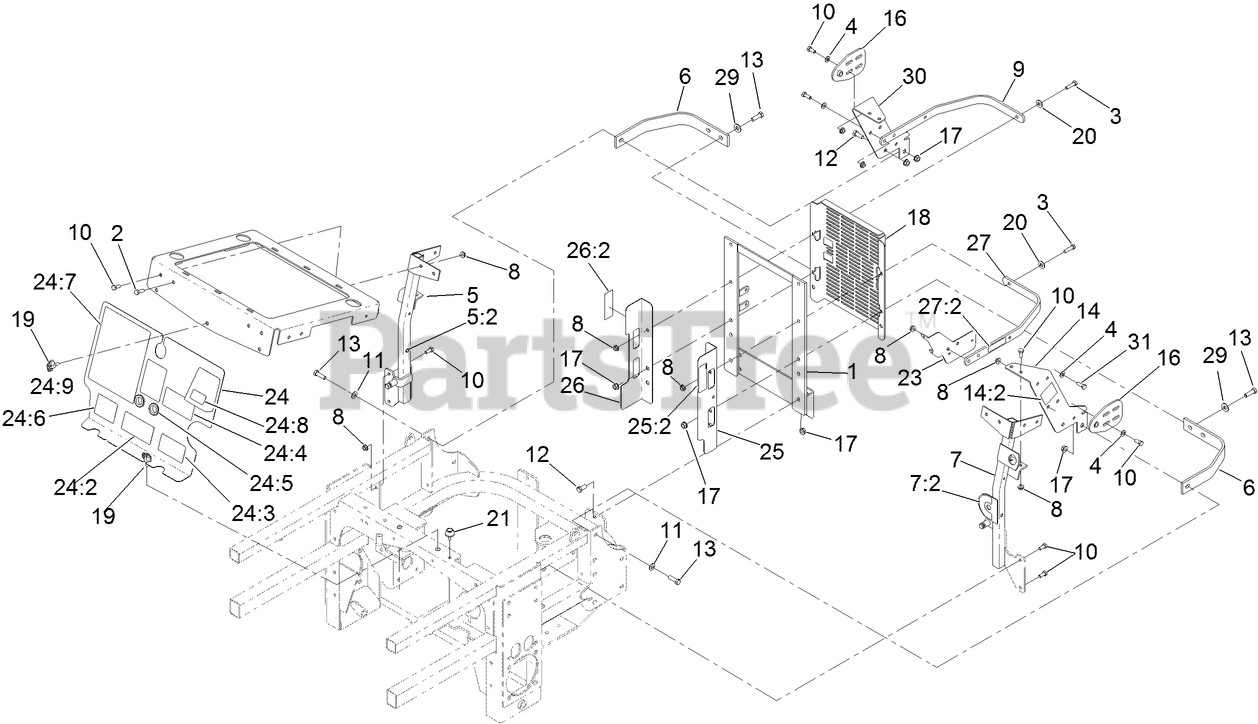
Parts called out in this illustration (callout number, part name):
1	SUPPORT-RADIATOR, REAR
2	SCREW-HH
3	SCREW-HH
4	WASHER-PLAIN
5	RH RADIATOR BRACE ASM
5:2	NUT-CLINCH
6	STRAP-GUARD
7	LH RADIATOR BRACE ASM
7:2	DECAL-FUEL VALVE
8	NUT-HF
10	SCREW-HH
11	WASHER-FLAT
12	SCREW-HH
13	SCREW-HH
14	LH SUPPORT BRACKET ASM
14:2	DECAL-FUSE
16	PLATE-PIVOT, HOOD
17	NUT-HHF, WHIZ
18	SHIELD-COOLER
20	WASHER-FLAT
21	BUMPER-RUBBER
23	BRACKET-RELAY, FUSE
24	FRONT ENGINE SHIELD ASM
24:2	DECAL-DANGER, ROTATING DEVICES
24:3	DECAL-HYDRO BELT ROUTING
24:4	DECAL- WARNING, BUZZER
24:5	GROMMET-RUBBER
24:6	DECAL-CLUTCH BELT ROUTING
24:7	DECAL-CHECK SERVICE
24:8	DECAL-CAUTION
24:9	DECAL-COOLANT
25	GUARD-FAN, LH (CE)
25:2	DECAL-DANGER
26	GUARD-FAN, RH (CE)
26:2	DECAL-DANGER
27	TOP STRAP ASM
27:2	DECAL-RELAY
29	WASHER-FLAT
30	BRACKET-SUPPORT, RH
31	SCREW-HH
